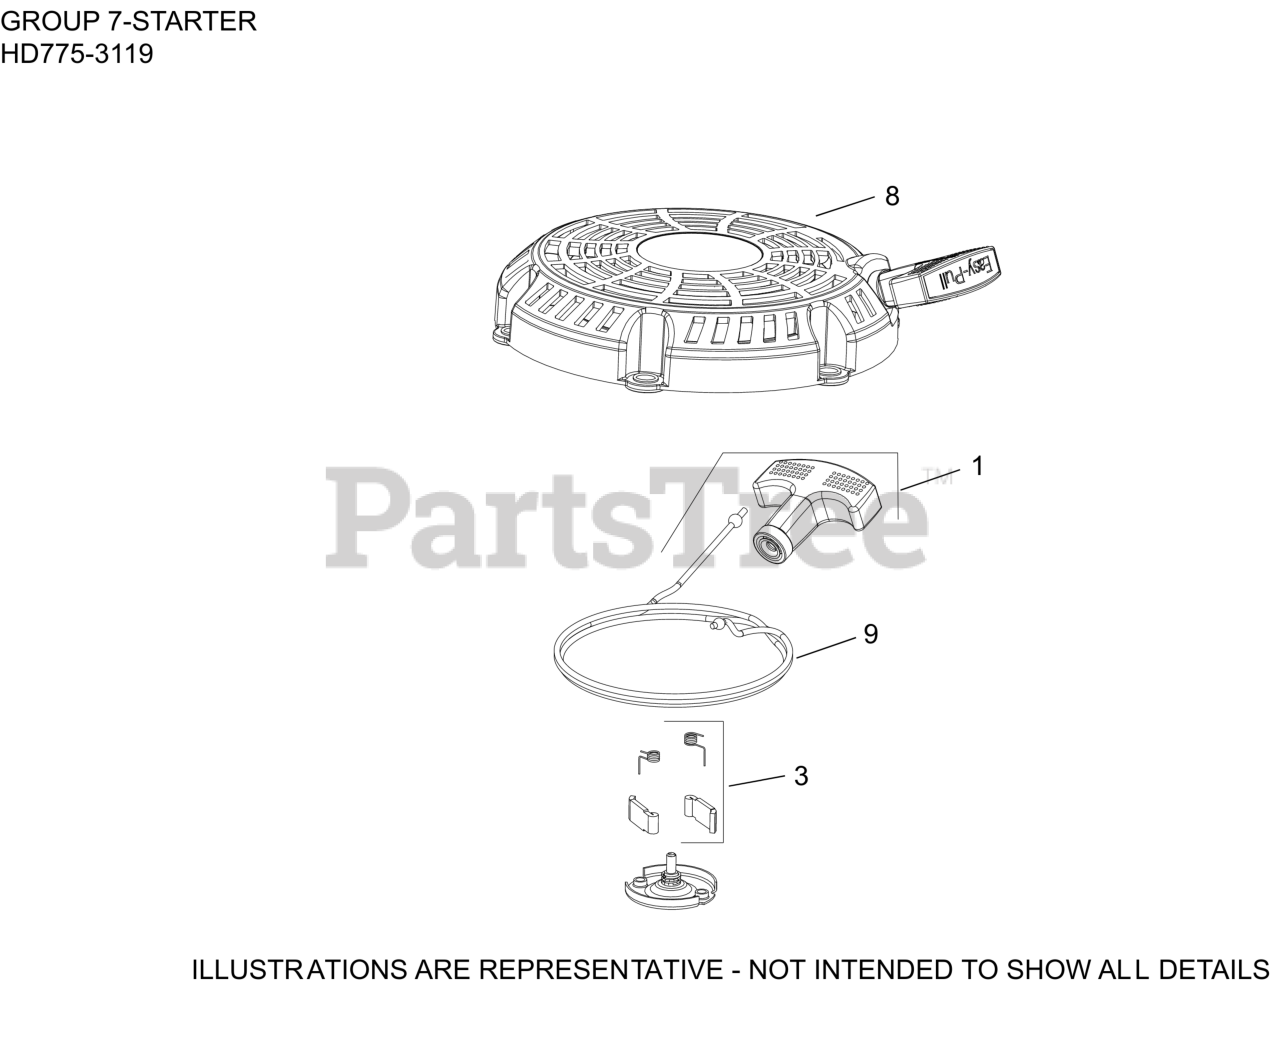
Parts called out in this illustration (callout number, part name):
1	KIT, STARTER ROPE W/HANDLE
3	KIT, PAWL REPAIR
8	STARTER ASSEMBLY, RETRACTABLE
9	KIT, STARTER ROPE W/HANDLE
